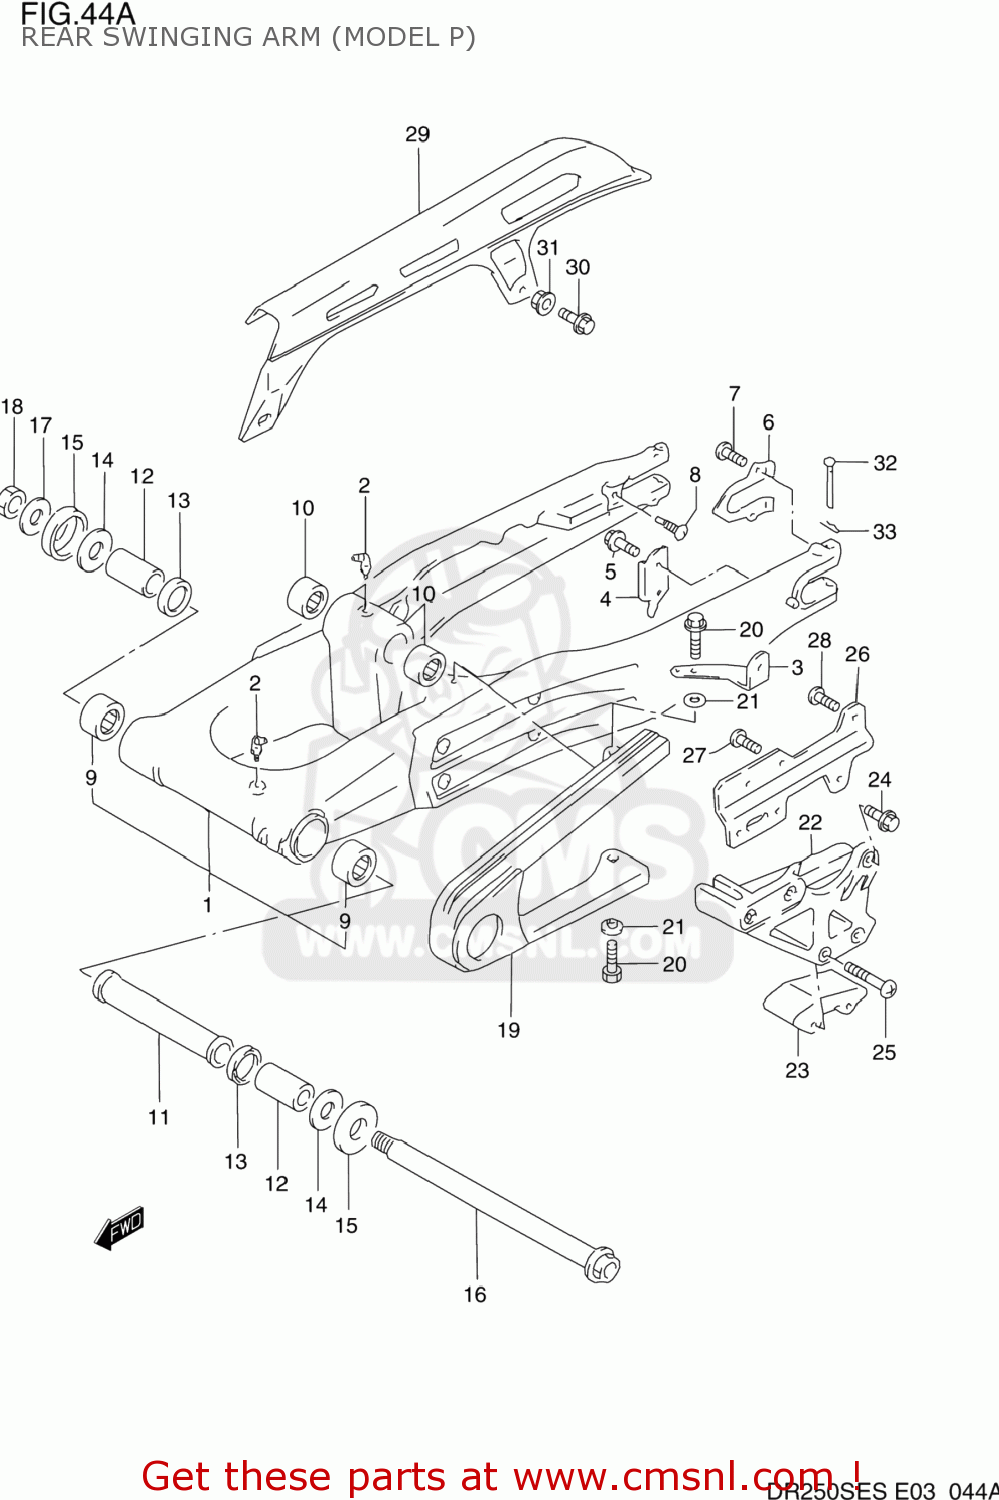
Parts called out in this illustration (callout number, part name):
1	SWING ARM ASSEMBLY,REAR
2	NIPPLE,GREASE
3	PLATE,CHAIN CASE FTG FR
4	PLATE,CHAIN CASE FTG RR
5	BOLT
6	PLATE,SWING ARM RR
7	SCREW (5X8)
8	SCREW (M10X21)
9	BEARING(22X29X30)
10	BEARING(20X27X23.5)
11	SPACER,SWING ARM PIVOT,CENTER
12	SPACER,SWGARM PIVOT BRG
13	SEAL,OIL(22X29X4)
14	WASHER
15	COVER,SWINGINGARM PIVOT
16	SHAFT,SWINGING ARM PIVOT
17	WASHER
18	NUT
19	BUFFER,CHAIN TOUCH DEFENSE
20	BOLT
21	WASHER
22	GUIDE,CHAIN
23	DEFENSE,CHAIN GUIDE
24	BOLT 6X16
25	SCREW
26	BRACKET,CHAIN GUIDE
27	BOLT 6X16
28	BOLT
29	CASE,CHAIN
30	BOLT
31	WASHER
32	PIN
33	CLIP
